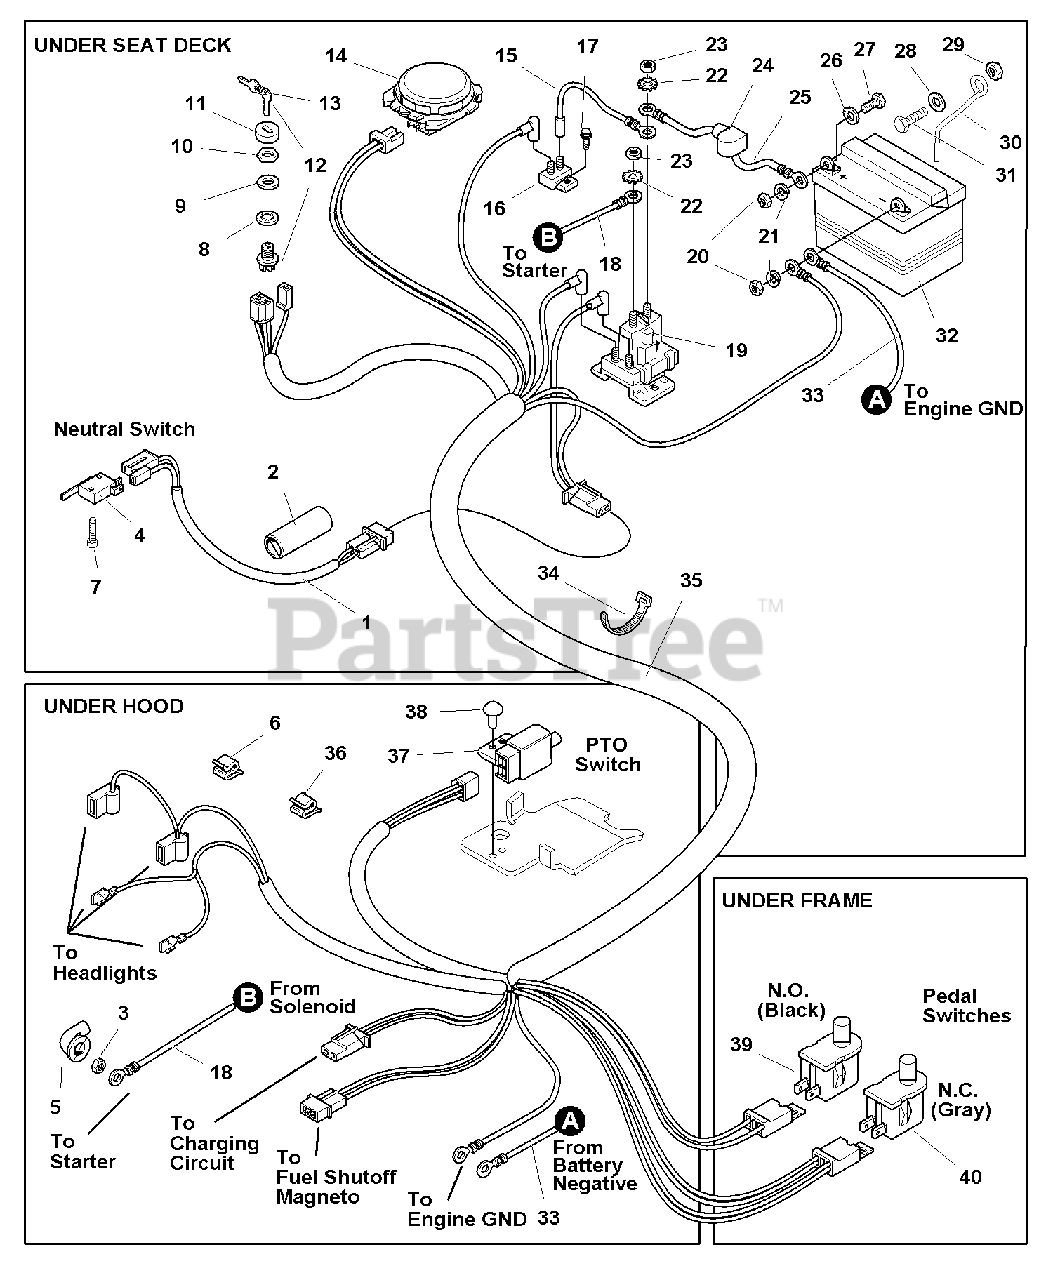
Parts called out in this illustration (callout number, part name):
1	WIRE ASSEMBLY
2	TUBE, Shrink
3	NUT, Hex Flange, Whiz Lock, 1/4-20
4	SWITCH, Neutral Safety
5	COVER, Terminal
6	CLIP, Tinnerman
7	CAPSCREW, Round Head, Phillips, #4 - 40 x 3/4
8	LOCKWASHER, Internal Tooth, 5/8
9	WASHER, 5/8
10	NUT, Hex, Flange, 5/8-32
11	COVER, Ignition
12	SWITCH, Ignition, 6-Pole (Includes Ref. 8, 9, 10, 11 & 13)
13	IGNITION KEY (Set of 2)
14	SWITCH, Seat, Gray Switch, Gray Retainer
14	SWITCH, Seat, Gray Switch, Black Retainer
15	WIRE ASSEMBLY
16	CIRCUIT BREAKER
17	CAPSCREW, Taptite Hex Washer Head, 1/4-20 x 5/8
18	CABLE, # 6 x 42-1/2 long (Solenoid to Starter)
19	SOLENOID
20	NUT, Hex, 1/4-20
21	LOCKWASHER, 1/4
22	LOCKWASHER, External Tooth, 5/16
23	CABLE, # 6 x 10 Long, with 2 Ring Terminals
24	BOOT, Insulator
25	NUT, Hex, 5/16-24 NF
26	WASHER, Plain, 1/4
27	CAPSCREW, Hex Head, 1/4-20 x 3/4
28	WASHER, Plain, 5/16
29	NUT, Hex Nylon Lock, 5/16-18
30	ROD, Battery Hold Down
31	CAPSCREW, Hex Head, 5/16-18 x 3/4
33	CABLE, # 6 x 52-1/2 long (Battery to Ground)
34	TIE-SELF LOCKING (Qty 2 on Gear Models)
35	HARNESS, Wiring
36	CLIP, Wire
37	SWITCH, Neutral Start
39	SWITCH, Pedal, N.O., Black
40	SWITCH, Pedal, N.C., Gray
